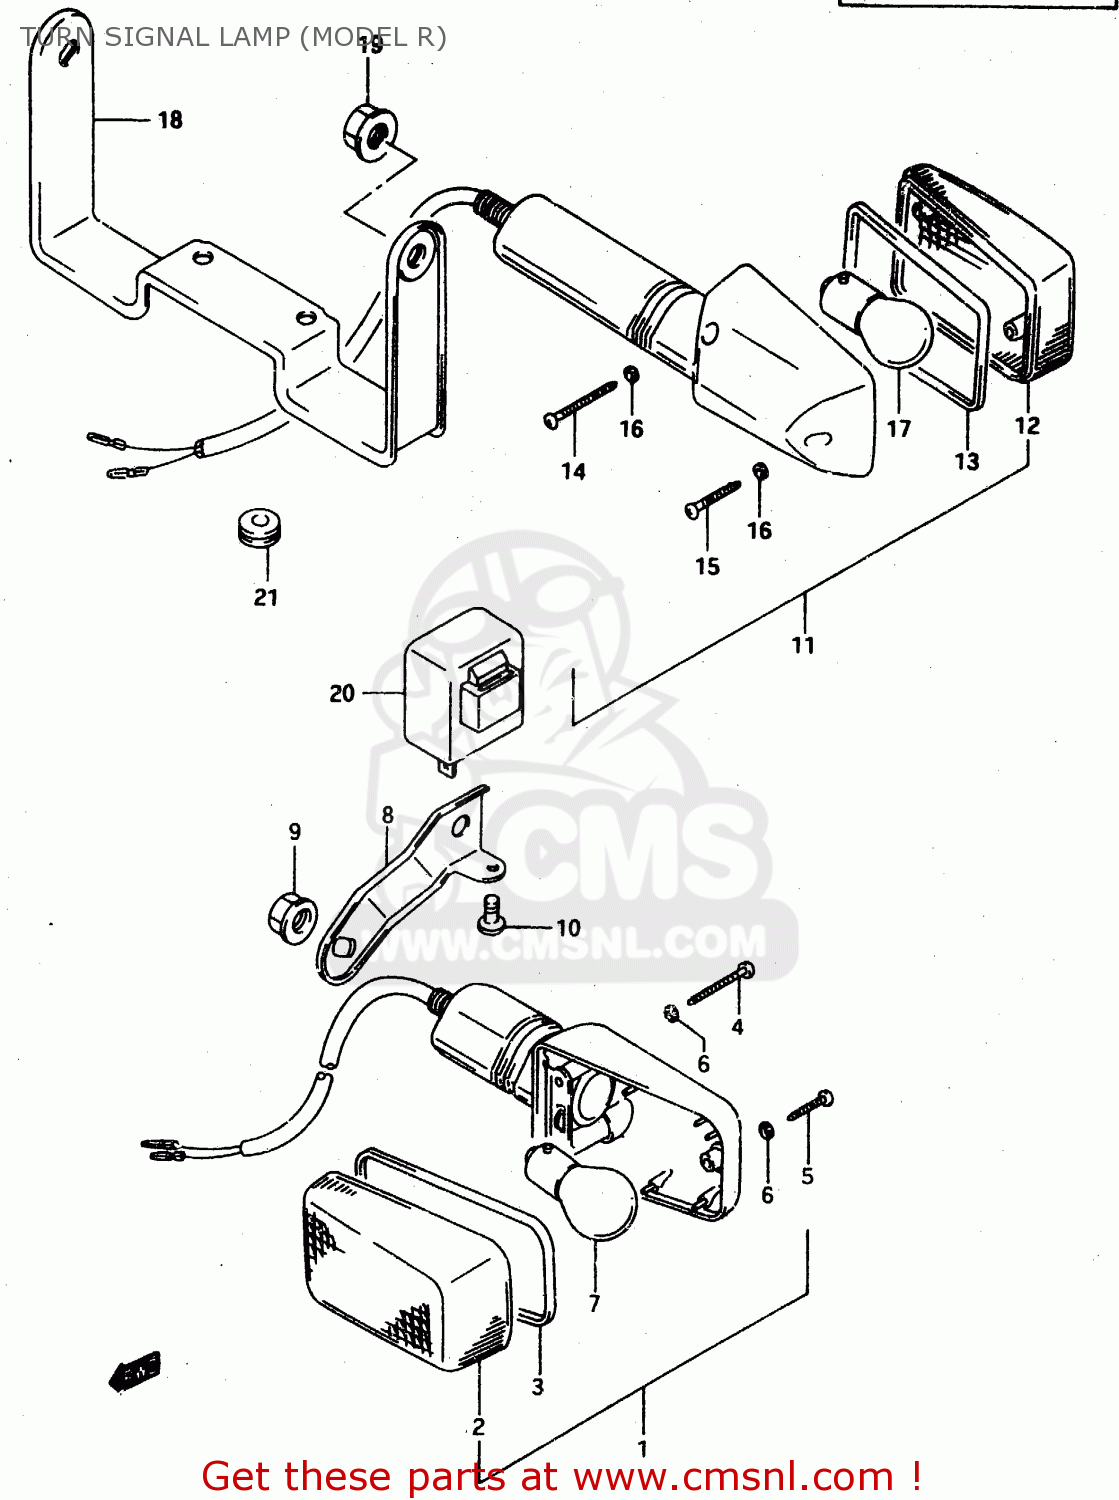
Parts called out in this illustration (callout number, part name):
1	LAMP ASSY,FR TURN SIGNAL
2	LENS
3	GASKET (NAS)
4	SCREW(3X30)
5	SCREW
6	GASKET (NAS)
7	BULB(12V21W)
8	BRACKET,FRONT TURN SIGNAL
9	NUT
10	SCREW
11	LAMP ASSY, REAR TURNSIGNAL
12	LENS
13	GASKET (NAS)
14	SCREW(3X30)
15	SCREW
16	GASKET (NAS)
17	BULB(12V21W)
18	BRACKET, REAR TURN
19	NUT
20	RELAY ASSY,TURNSIGNAL LAMP
21	GROMMET
